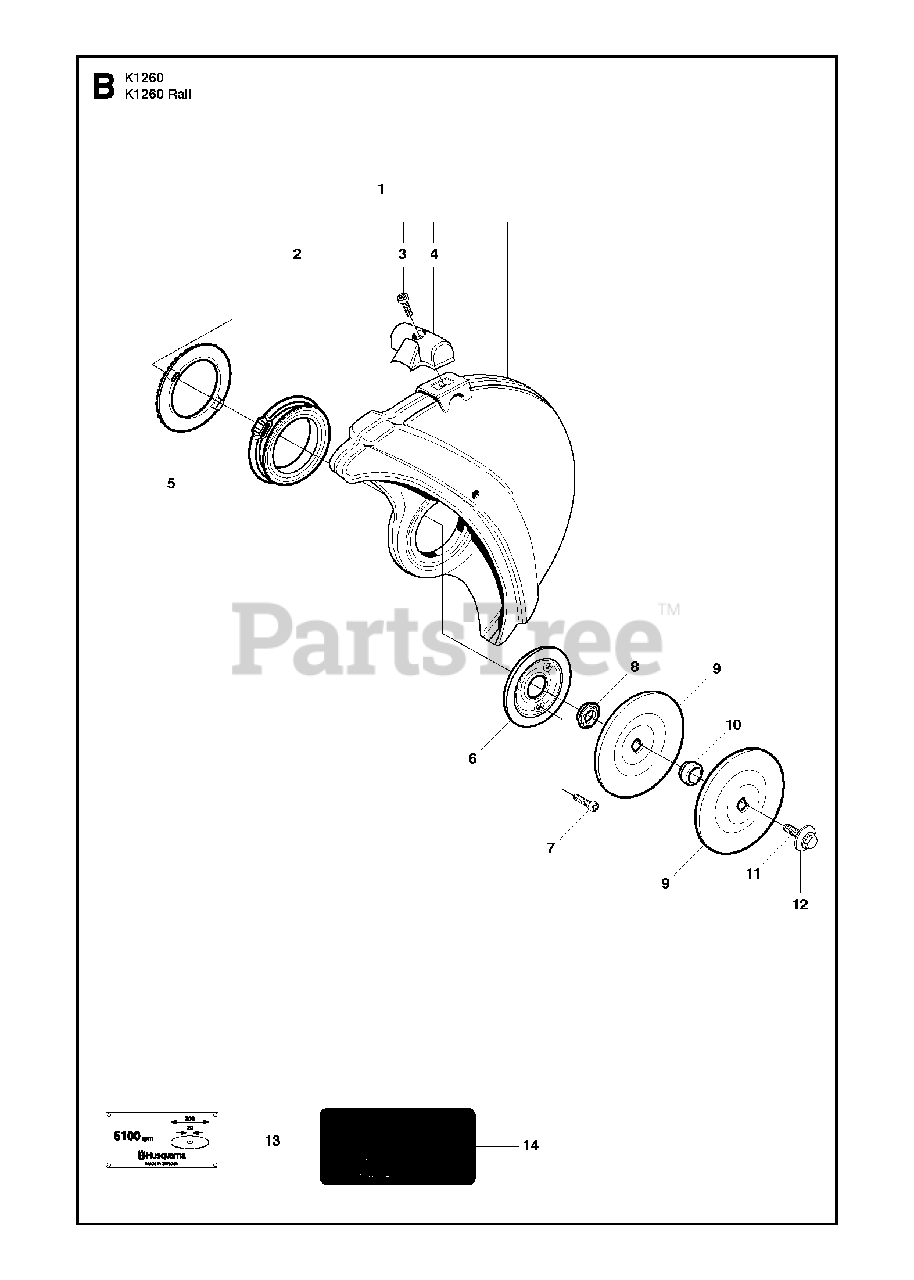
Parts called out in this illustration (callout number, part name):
1	BLADE GUARD"14"". Incl. 2 - 4"
1	BLADE GUARD"16"". Incl. 2 - 4"
1	BLADE GUARD"14"" Rail, Incl. 2 - 4"
1	BLADE GUARD"16"" Rail, Incl. 2 - 4"
3	SCREW ITXSCM
7	SCREW ITXSCM
8	SUPPORT FLANGE
9	FLANGE WASHERDiam 105
9	FLANGE WASHERDiam 119
10	KITDiam 22,2
10	BUSHINGDiam 30,5
13	LABEL"14"". Diam 20 mm"
13	LABEL"14"". Diam 1"""
13	LABEL"16"". Diam 20 mm"
13	LABEL"16"". Diam 1"""
14	DECAL"Japan 14"""
14	DECAL"Japan 16"""
